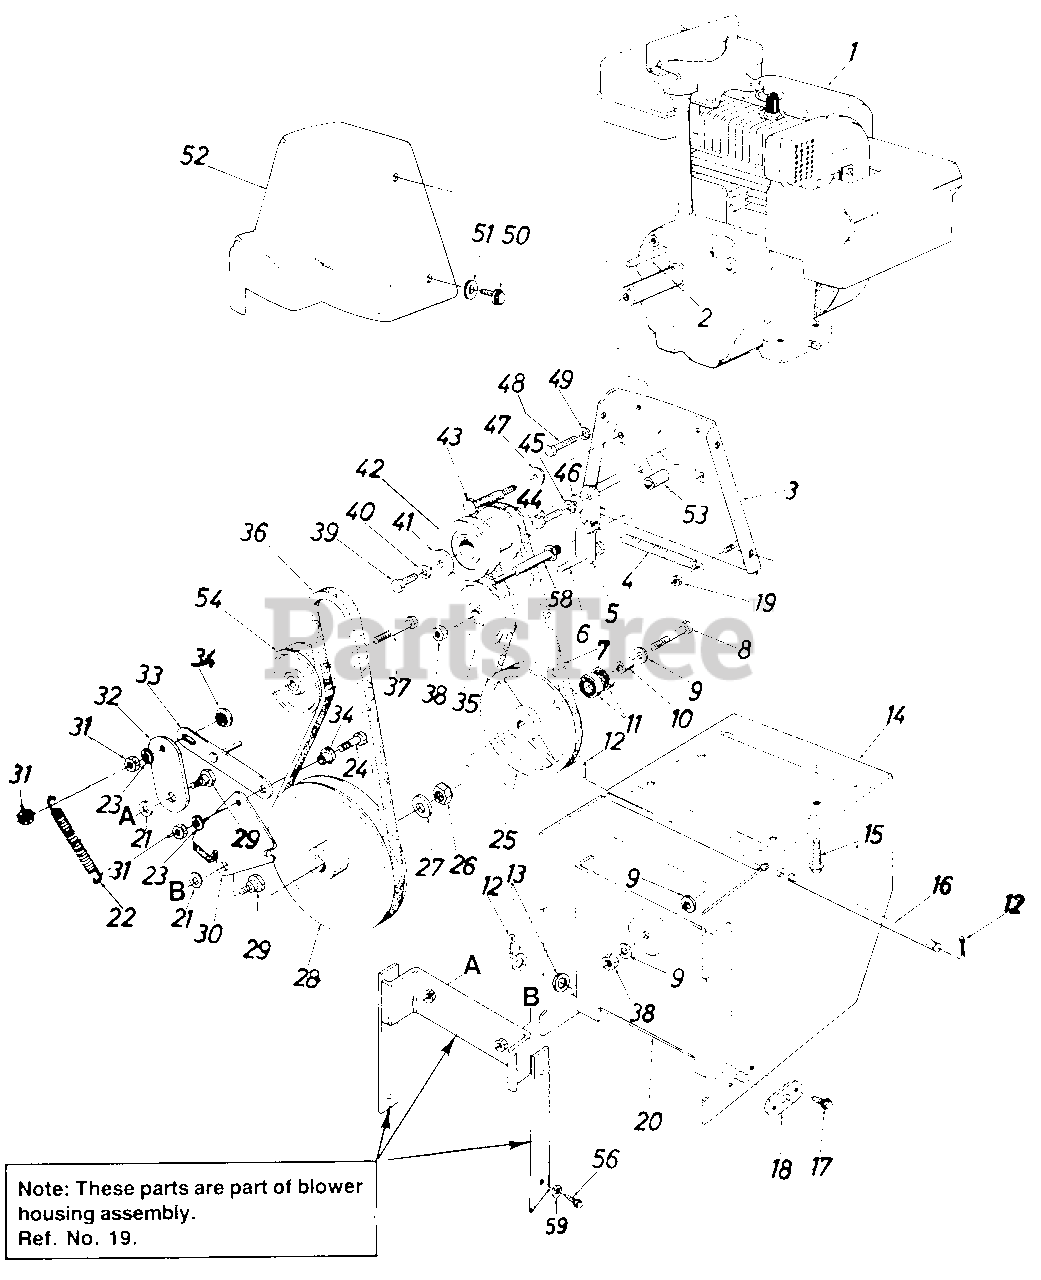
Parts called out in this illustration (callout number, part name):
1	Engine
2	Sq. Key 3/16" x 1.50" Lg. (420 & 524)
3	Engine Plate Ass'y.
4	Extension Spring .50" O.D. x 3.97" Lg.
5	Drive Clutch Idler Brkt.
6	Hex Bolt 3/8-24 x 1.25" Lg.
7	"V"-Belt
8	Hex Bolt 3/8-24 x 1.50" Lg.
9	Bell-Wash. .40" I.D. x .88" O.D. x .06
10	Spacer .38" I.D. x .62" O.D. x .75" Lg.
11	Ball Brg. .62" I.D. x 1.38" O.D. x .44
12	Cotter Pin 3/32" Dia. x .75" Lg.
13	Fl-Wash. .53" I.D. x 1.00" O.D. x .1 25
14	Frame Ass'y.
15	Hex Wash. Hd. Self-Tap Scr. 3/8-16 x 1.25" Lg.
16	Shaft .50" Dia. x 9.50" Lg.
17	Hex Wash. Hd. Self-Tap Scr. 1/4-20 x .50" Lg.
18	Axle Bracket
19	Hex L-Nut 1/4-20 Thd.
20	Drive Pulley Support Brkt. Ass'y.
21	Bell-Wash. .40" I.D. x 1.13" O.D.
22	Extension Spring .56" O.D. x 4" Lg.
23	L-Wash. 3/8" I.D.
24	Hex Scr. 3/8-16 x 1.25" Lg.
25	6.00" O.D. Drive Pulley Ass'y.
26	Hex Jam Cent. L-Nut 5/8-18 Thd.
27	Fl-Wash. .64" I.D. x .94" O.D. x .06
28	1/2" V-Pulley .625" I.D. x 7.50" O.D. (420 & 524)
29	Shld. Bolt .625" Dia. x .170" Lg. (3/8-16)
30	Brake Bracket Ass'y. (420 & 524)
31	Hex Ins. L-Nut 3/8-16 Thd.
32	Auger Clutch Idler Brkt.
33	Brake Linkage Ass'y.
34	Shld. Spacer .625" I.D.
35	Fl-ldler Pulley 2.25" O.D.
36	"V''-Belt (420 & 524)
37	Hex Bolt 3/8-16 x 2" Lg.
38	Hex Ins. Jam L-Nut 3/8-24 Thd.
39	Hex Bolt 3/8-24 x 1.50" Lg.
40	L-Wash. 3/8" I.D.
41	Bell-Wash. .40" I.D. x 1.25" O.D. (420 & 524)
42	Double Groove Engine Pulley (420 & 524)
43	Shld. Scr. .498" x 3.0" Lg. (420 & 524)
44	Hex Bolt 5/16-24 x 1.00" Lg.
45	L-Wash. 5/16" I.D.
46	Shld. Spacer .27" Lg. I.D.
47	Bell-Wash. .40" I.D. x .88" x .06
48	Hex Bolt 5/16-24 x .62" Lg.
49	L-Wash. 5/16" I.D.
50	Hex Wash. Hd. Self-Tap Scr. 1/4-20 x .50" Lg.
51	Fl-Wash. .28" I.D. x .75" O.D. x .06
52	Belt Cover
53	Spacer (420 & 524)
54	Fl-ldler Pulley 2.75" O.D.
56	Hex Wash. Hd. Self-Tap Scr. 3/8-16 x .75" Lg.
58	Stud 3/8-16 x 3.37" Lg.
59	L-Wash. 3/8" I.D.-H.D.
